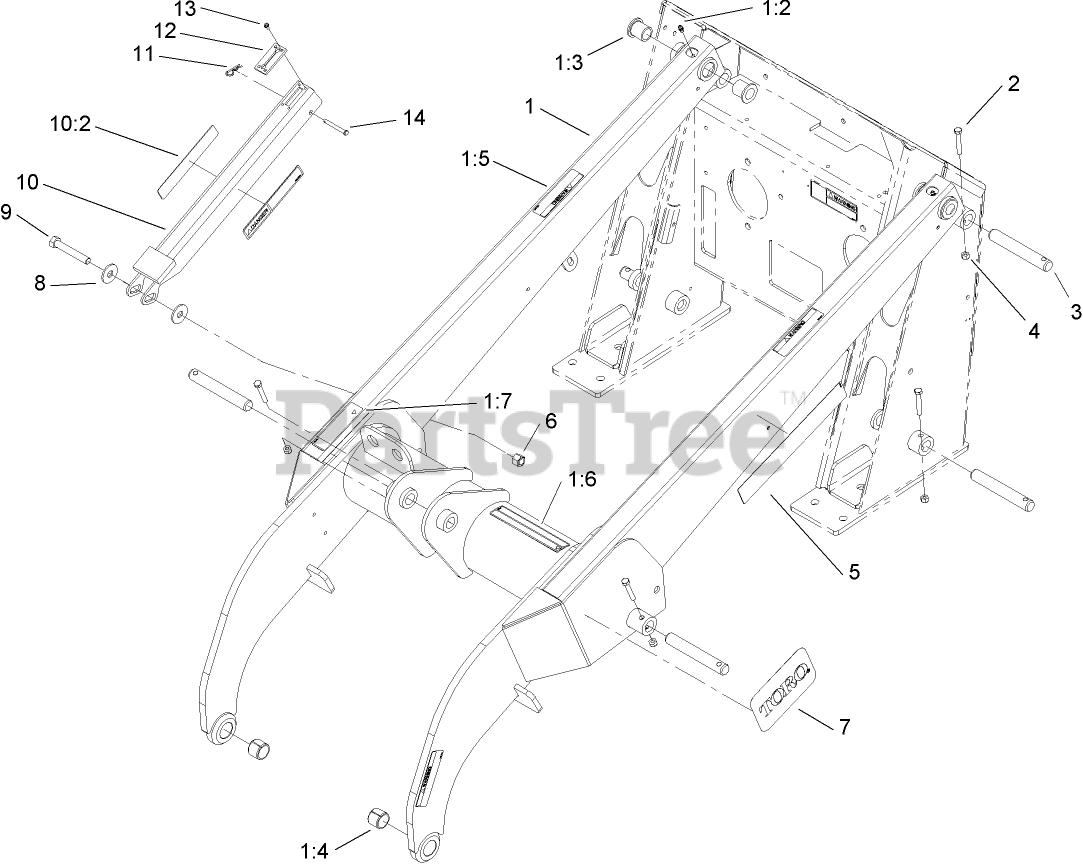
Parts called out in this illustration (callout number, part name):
1	LOADER ARM ASM
1:2	FITTING-GREASE
1:3	BUSHING
1:4	BUSHING-TENSION
1:5	DECAL-PINCH
1:6	DECAL-CAUTION
1:7	DECAL-CAUTION
2	SCREW-HH
3	PIN-LOCKING
4	NUT-LOCK, NI
5	Decal
6	NUT-LOCK, NI
8	WASHER-RUBBER
9	SCREW-HH
10	LOCKING ARM ASM
10:2	DECAL-DANGER
11	PIN-COTTER
12	STOP-RUBBER
14	PIN-CLEVIS
